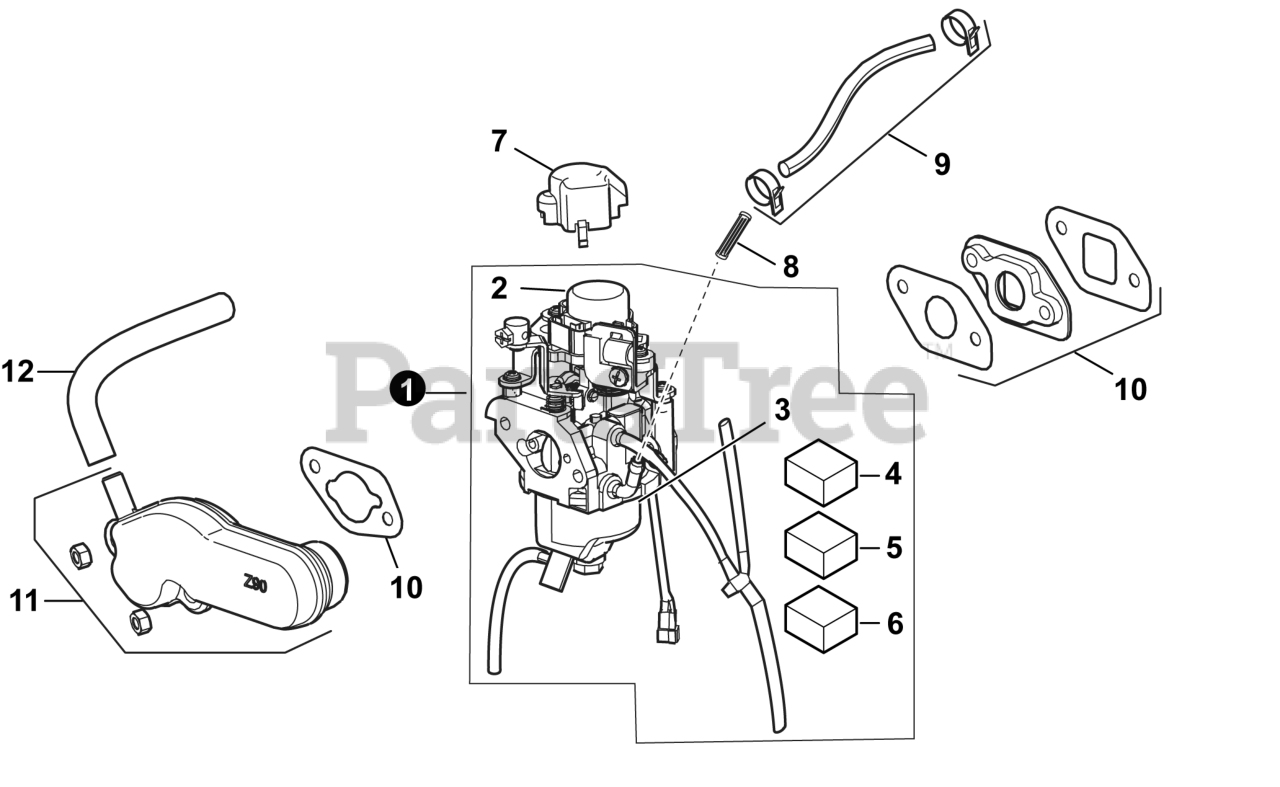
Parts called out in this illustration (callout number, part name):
1	CARBURETOR ASSY.
2	MOTOR, STEPPER
3	GASKET, CARB BOWL
4	KIT, BOWL
5	KIT, FLOAT
6	KIT, MAIN JET
8	STRAINER, FUEL
9	HOSE, FUEL
10	GASKET SET, INTAKE
11	DUCT, AIR CLEANER INTAKE
12	TUBE, BREATHER
